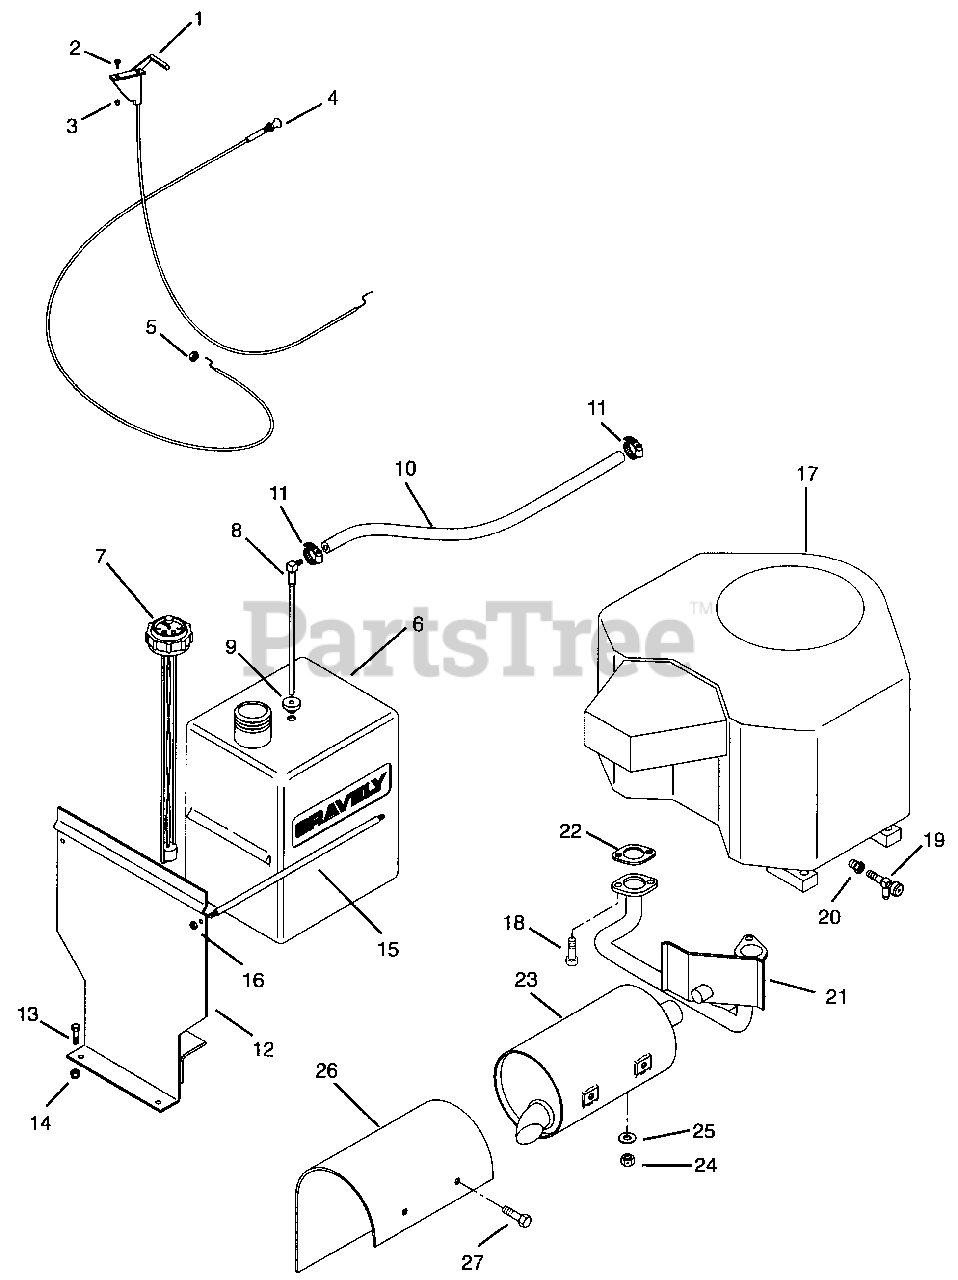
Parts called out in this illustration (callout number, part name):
1	Throttle Cable
2	Screw-Machine 10-24 x .50
3	Nut-Locking Nylon 10-24 W/Insrt
4	Control, Choke
5	Nut-Jam .375-24
6	Tank, Fuel
7	Gauge, Fuel
8	Fitting, Tank
9	Bushing
10	Gas Line-Bulk
11	Hose Clamp
12	Weldment, Tank Bracket
13	Bolt-Hex .31-18 x .75 Grade 5
14	Nut-Locking-Nylon .31-18
15	Rod, Tank
16	Nut-Locking-Center .25-20
17	Engine, Kohler CV20
17	Engine, Kohler CV 25 HP
18	Screw-Socket Head M8-1.25 x 20 mm
19	Cock, Oil Drain
20	Adapter, Oil Drain
21	Manifold, Kohler CV18-25
22	Gasket, Exhaust
23	Muffler (Includes 09066300 Heat Shield)
24	Nut-Locking-Center .38-16
25	Washer-Flat-Steel .438 x 1.00 x .083
26	Heat Shield (Included with 09065600 Muffler)
27	Screw-Tapping w/Washer
